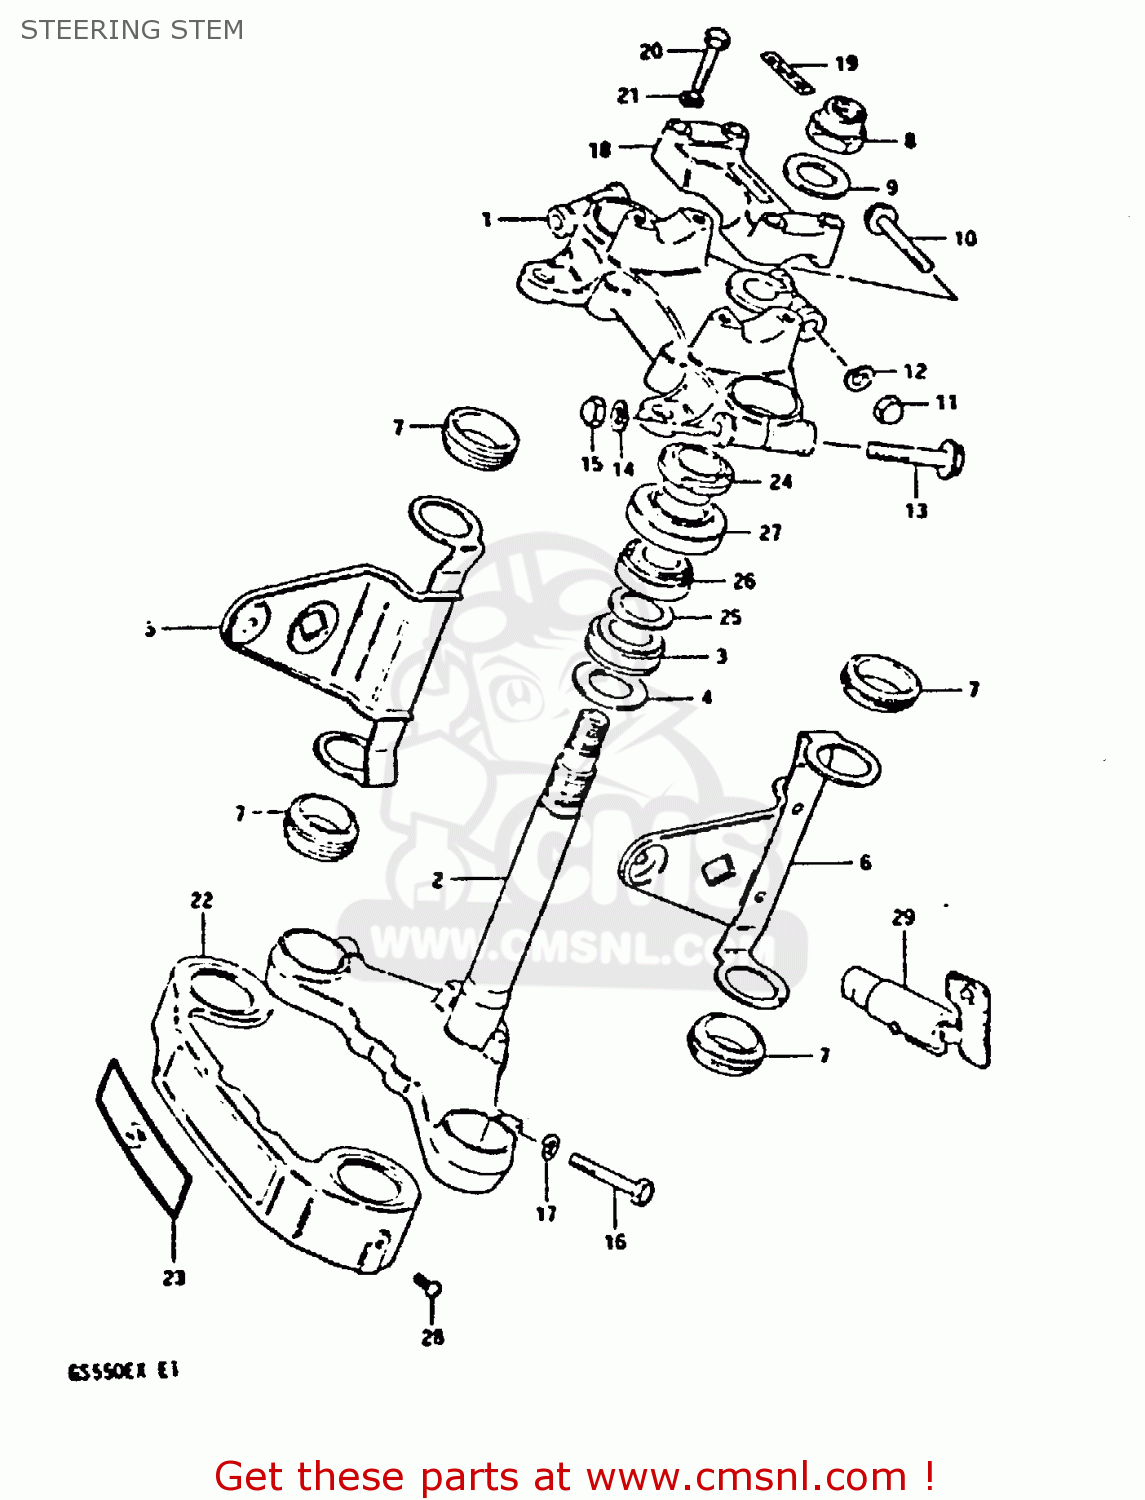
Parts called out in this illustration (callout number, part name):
1	HEAD,STEERING STEM
2	STEM,STEERING
3	BEARING
4	WASHER,THRUST
5	BRACKET,HEADLAMP,RIGHT
6	BRACKET,HEADLAMP,LEFT
7	CUSHION,HEADLAMP BRACKET
8	NUT,FR FORK UPR BRACKET
9	WASHER
10	BOLT
11	NUT,M8X1.25X12
12	LOCK WASHER
13	BOLT 10X55
14	LOCK WASHER
15	NUT
16	BOLT 10X40
17	LOCK WASHER
18	HOLDER,HANDLEBAR
19	EMBLEM,HANDLE CLAMP
20	BOLT
21	LOCK WASHER
22	COVER,FRONT FORK
23	EMBLEM
24	NUT,STEERING STEM
25	WASHER(18.5X24X1)
26	TAPER,ROLLER BEARING
27	DUST SEAL,STEERING,UPPER
28	SCREW 5X6
